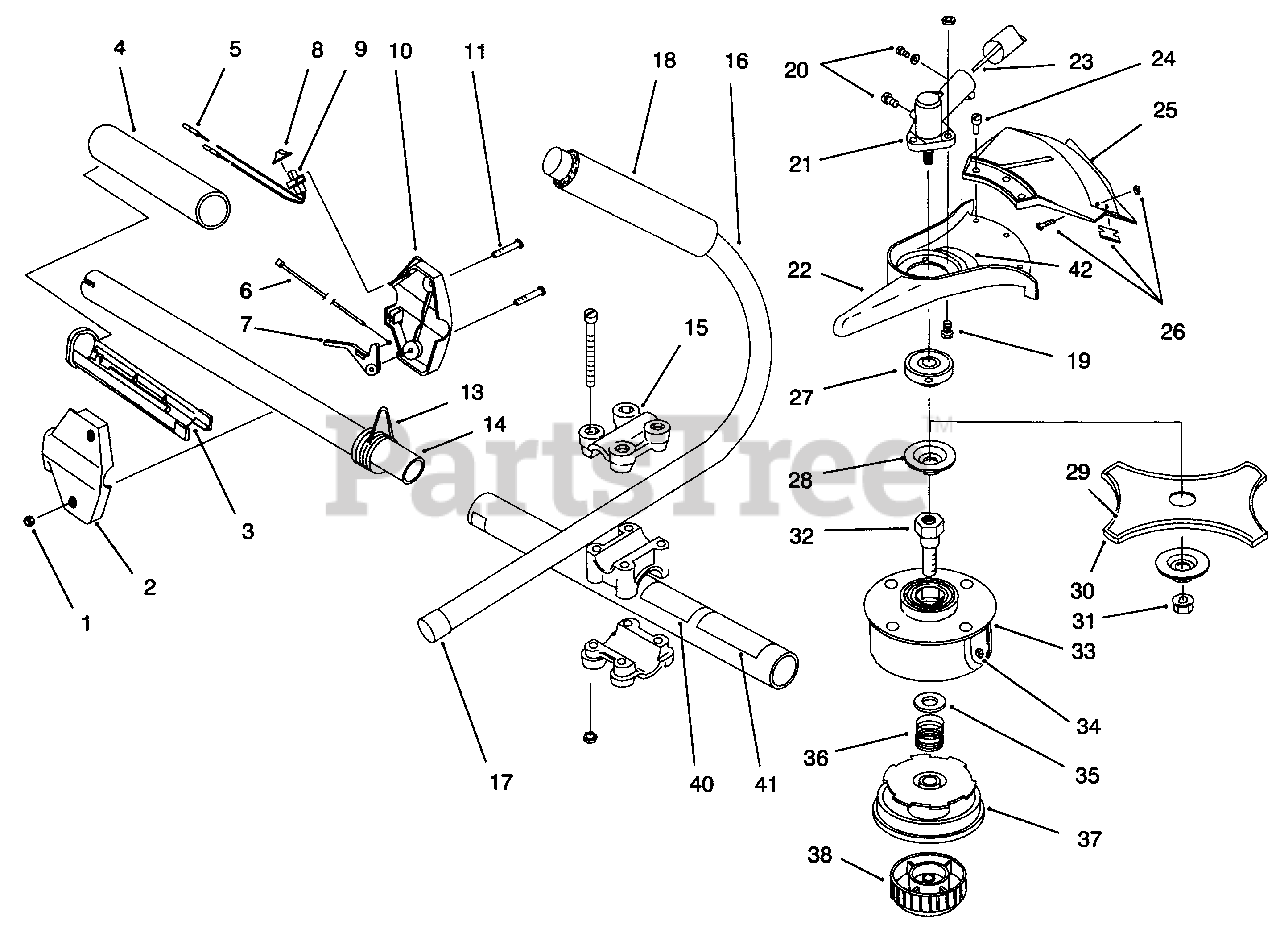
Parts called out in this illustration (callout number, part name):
1	Lock Nut
2	R.H. Housing
5	Lead Wire Asm.
6	Throttle Cable
7	Throttle Lever
8	Switch Cap
10	L.H. Housing
11	Hex Head Screw
13	Shoulder Strap Clamp
14	Drive Shaft Housing Asm.
15	Handle Bracket Asm. (Incl.4 Screws & 4 Nuts)
16	J-Handle Asm. (Incl. Ref. #17-18)
17	Tube Closure
19	Guard Mount Screws & Nuts
20	Mount Hardware & Plug
21	Gear Box Asm.
22	Guard Mount
23	Flexible Drive Shaft
24	Guard Mount Screws
25	Guard and Blade Asm.
26	Blade Asm.
27	Blade Driver
28	Blade Retaining Washer
29	Blade Cover
30	Blade (Incl. Ref. #29)
31	Lock Nut
32	Spool Shaft
33	Outer Spool & Eyelet Asm.
35	Retainer
37	Inner Reel
38	Bump Head Knob Asm.
40	Decal-Safety Symbols
41	Decal-Brushcutter Symbol
42	Decal-Warning
